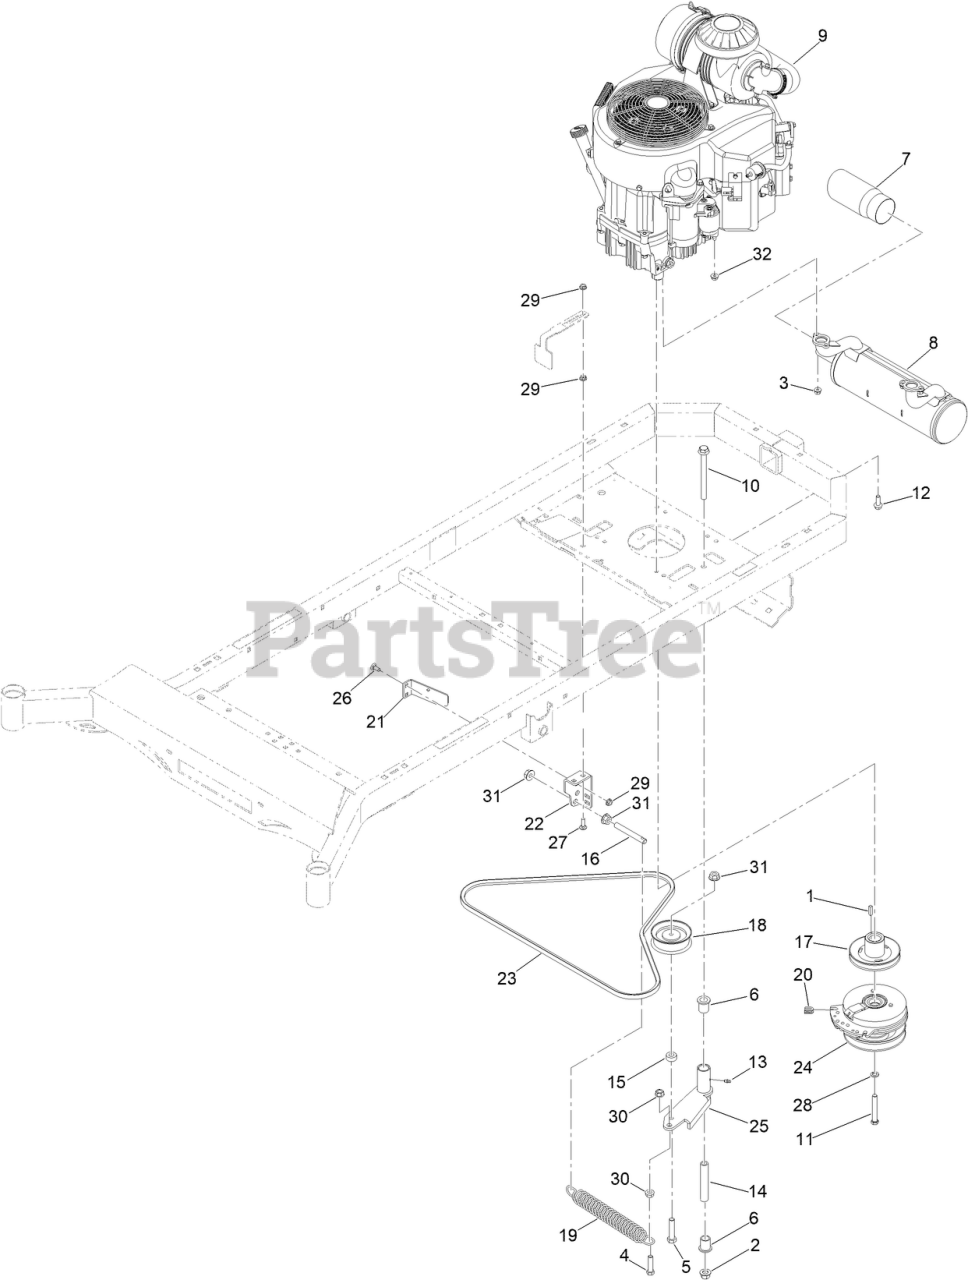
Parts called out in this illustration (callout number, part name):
2	NUT-LOCK
3	NUT-HF
4	SCREW-HH
5	SCREW-HH
6	3/4IN ID X15/16IN OD X 1-1/8IN FLNG BUSH
7	MWR CHROME EXHAUST TIP
8	EXHAUST SYSTEMKAWI FX801/FX850/FX850EFI
9	KAWASAKI FX801V ENGN
10	1/2-13 X 5-1/2 HEX FLANGE BOLT GR 8 ZY
11	7/16-20 X 3 HEX C/S GR 8 ZC YELLOW
12	3/8-16 X 1-1/8 IND HWH W/SERR TRI LOB ZY
13	1/4IN DRIVE TYPE GREASE FITTING YZ
14	MWR INNER IDLER SPACER
15	MWR PULLEY SPACER
16	MWR PUMP IDLER SPRING TENSIONER
17	MWR HYDRAULIC PUMP DRIVE PULLEYA BELT
18	4IN DIESEL AND ECONOMY MWER IDLER PULLEY
19	MWR DECK SPRING
20	MWR CLUTCH ROTATION STOP BRKT SLEEVE
21	MWR CLUTCH ANTIROTATION BRKT BLACK
22	MWR PUMP IDLER TENSIONING BRKT BLACK
23	PUMP BELT SRT MODELS A X 69.25IN EFF L
24	WARNER PTO CLUTCH
25	4IN PUMP IDLER PULLEY ARM ASSY
26	BOLT-CARR
27	BOLT-CARR
28	WASHER-LOCK
30	NUT-HF
31	NUT-HHF
32	NUT-HF
